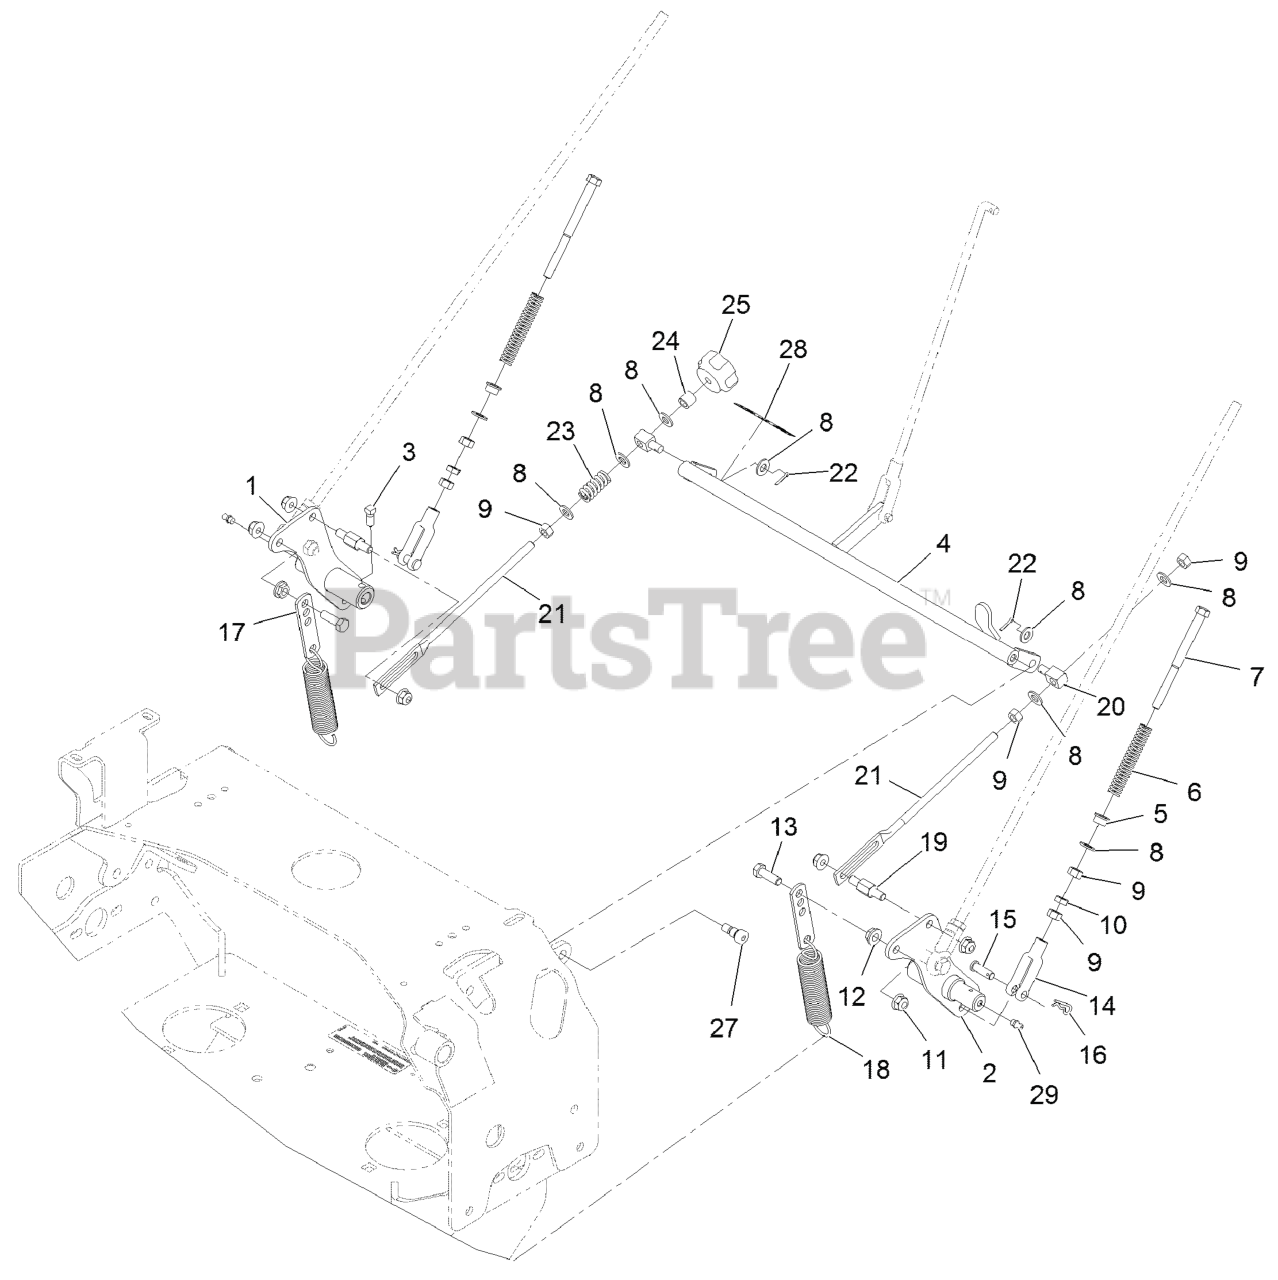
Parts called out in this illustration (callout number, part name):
1	WELD, MOTION CONTROL, RT
2	WELD, MOTION CONTROL, LT
3	SCREW-SET
4	WELD, SPEED CONTROL
5	BUSHING-FLANGED
6	SPRING,COMPRESSION (NEUT)
7	BOLT-RETURN, NEUTRAL
8	WASHER-PLAIN
9	NUT-HEX
10	NUT-JAM
11	NUT-HF, NI
13	SCREW-HH
14	YOKE-ADJUSTABLE
15	PIN-CLEVIS
16	PIN-COTTER
17	TAB-SPRING, EXTENSION
18	SPRING-EXTENSION
19	PIN, MOTION CONTROL
20	SWIVEL-ADJUSTABLE, SHORT
21	LINK-CONTROL, SPEED
22	PIN-COTTER
23	SPRING-COMPRESSION
25	KNOB-TRACKING
27	SCREW-HSH
28	DECAL-TRACKING ADJUSTMENT
29	FITTING-GREASE
